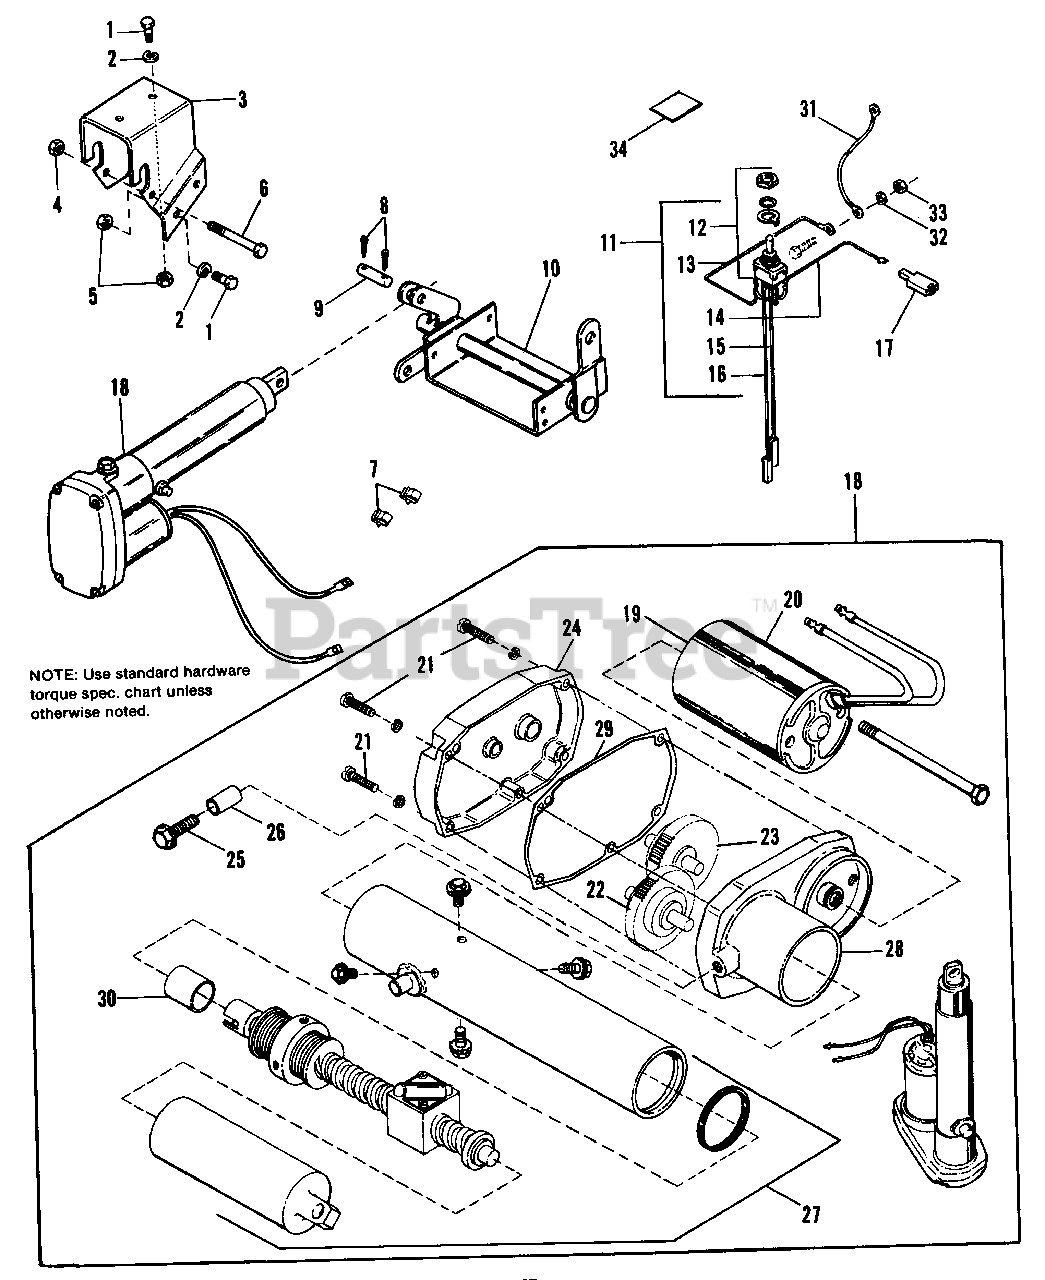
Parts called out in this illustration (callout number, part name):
1	CAPSCREW, Hex Hd., 5/16-18 x 3/4
2	LOCKWASHER, 5/16
3	BRACKET, Actuator
4	LOCKNUT, Hex, 5/16-18
5	NUT, Hex, 5/16-18
6	CAPSCREW, Hex Hd., 5/16-18 x 3-1/4
7	CLIP, Wire
8	PIN, Cotter, 1/8 x 3/4
10	ARM ASSY., Lift
11	HARNESS ASSY., Electric Lift
12	SWITCH ASSY., Electric
13	WIRE, Switch to Lift
14	WIRE, Switch to Lift
15	WIRE, Switch to Ground
16	WIRE, Switch to Ignition
17	CONNECTOR, Insulated
18	POWER LIFT ASSY.
19	BRUSH, w/Spring Set
20	12 VOLT DC MOTOR
21	SCREW, Fillister Hd.
22	GEAR ASSY., 4th
23	GEAR ASSY., 2nd & 3rd
24	COVER, Housing
25	CAPSCREW, Thd. Forming
27	BALL SCREW ASSY.
28	HOUSING, Motor
29	GASKET, Cover
31	WIRE, Ground
32	LOCKWASHER, 1/4
33	NUT, Hex, 1/4-20
34	DECAL, Lift Switch
